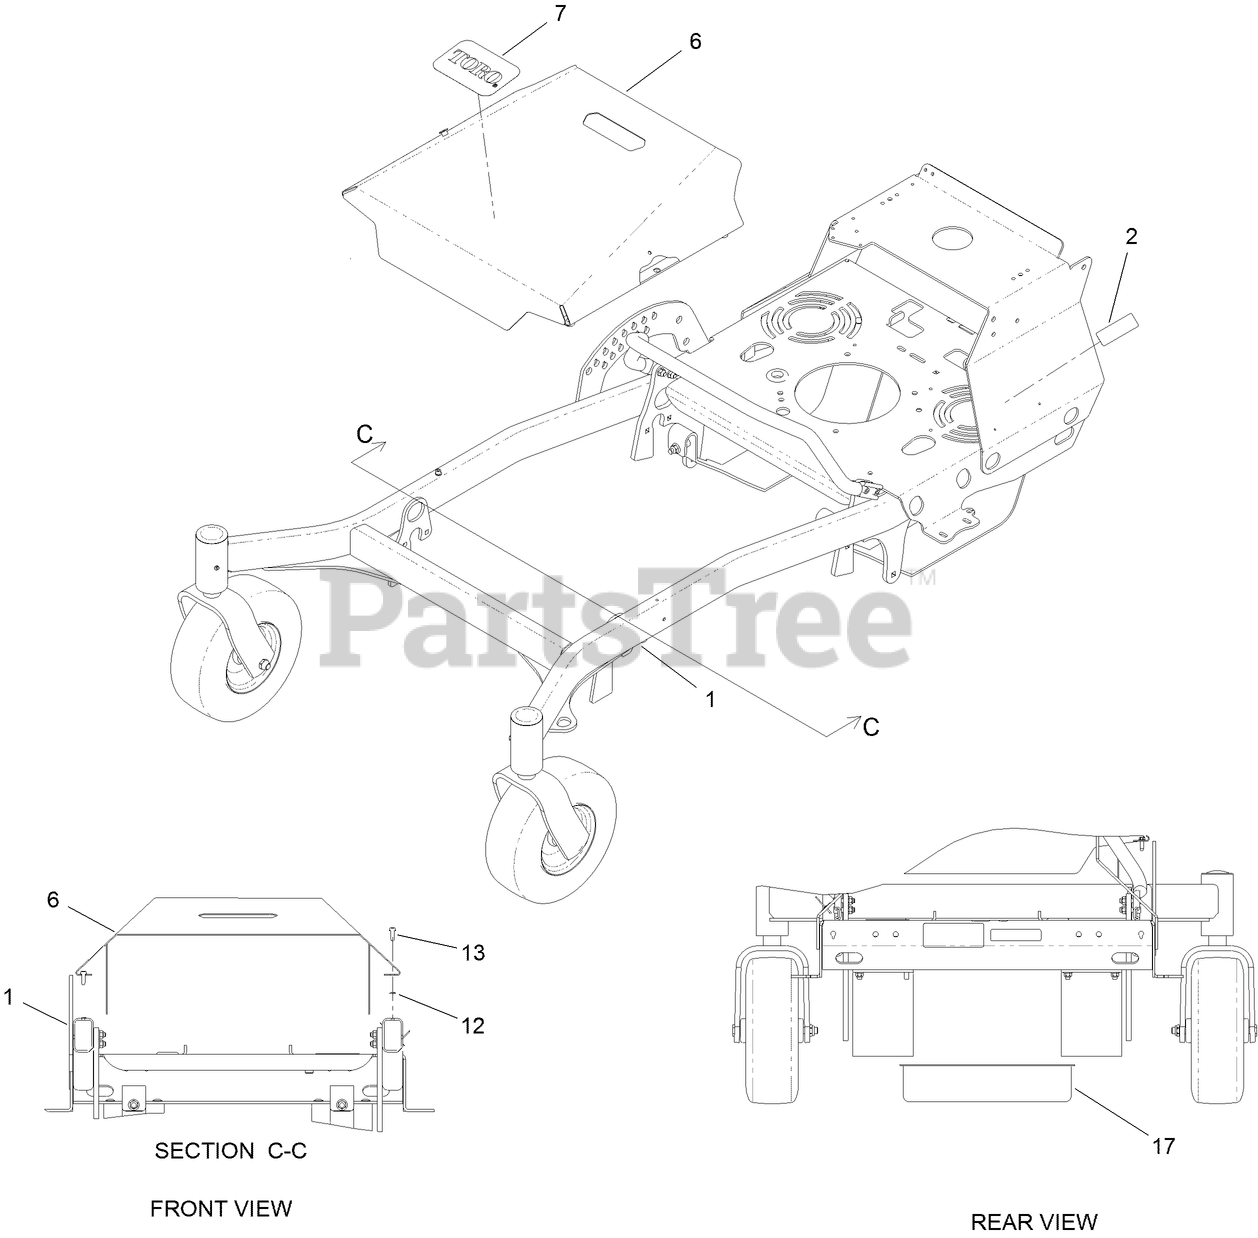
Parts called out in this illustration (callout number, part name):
1	FRAME ASSEMBLY
2	DECAL-EMISSIONS, EXPORT
6	COVER-DECK,WIDE
7	DECAL
12	NUT-RETAINING
13	SCREW-HWHTF
17	PLATE-GUARD, INTL
